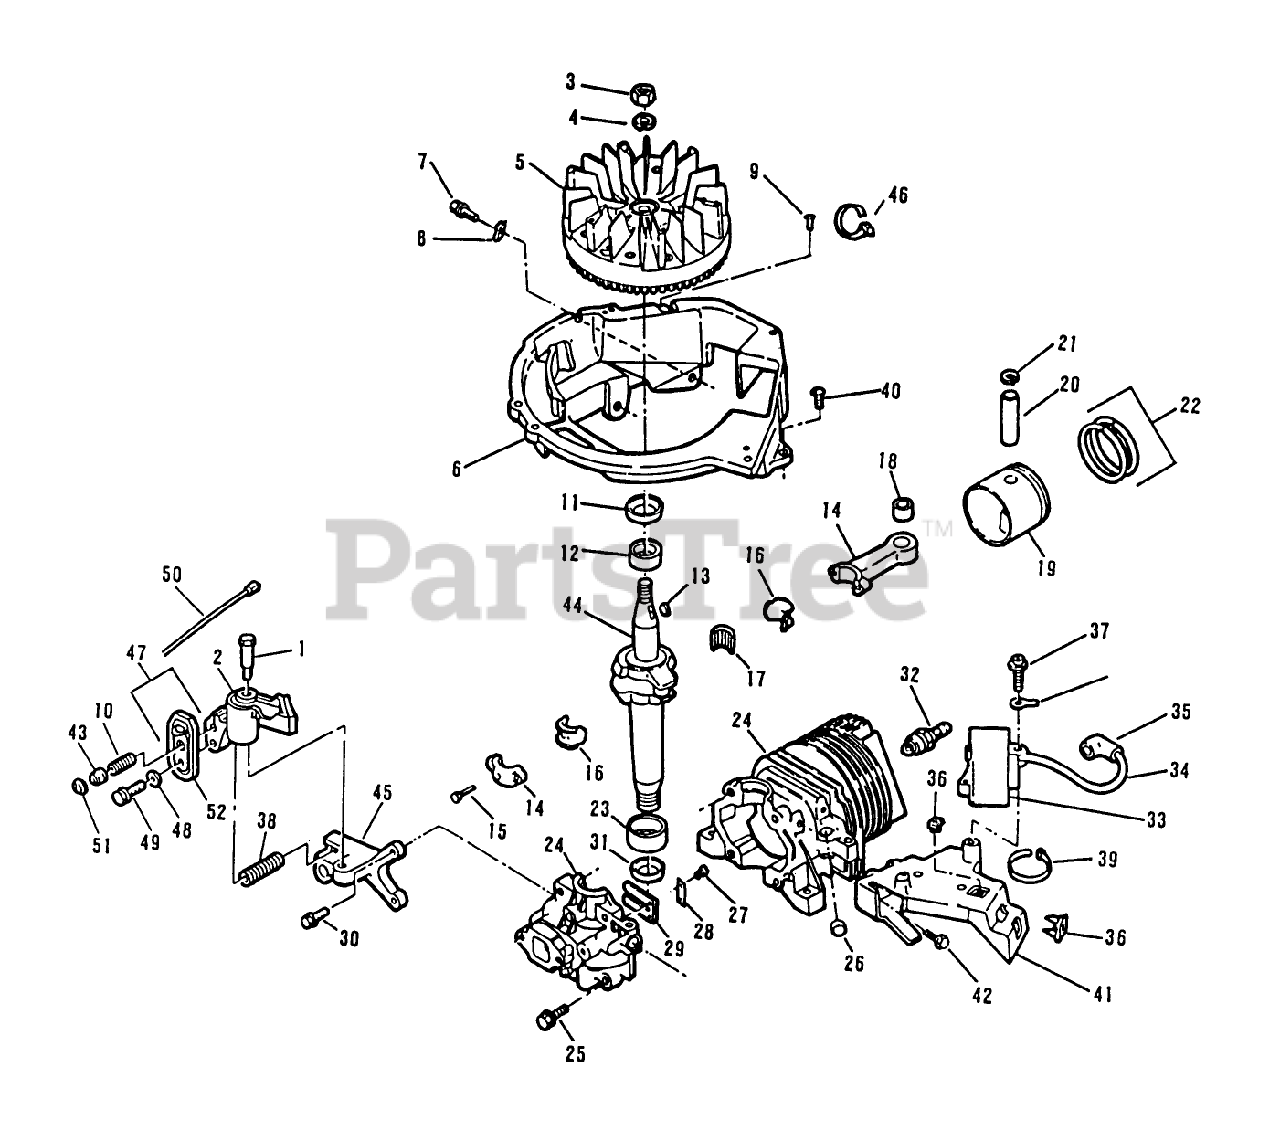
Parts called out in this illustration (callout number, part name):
3	NUT
5	FLYWHEEL ASSY F
6	BASE SHROUD F
7	SCREW-SEMS
9	SCREW F
10	SPRING
11	SEAL-OIL
12	BEARING V
13	KEY
15	SCREW-HSH
16	LINER ASM
17	BEARING-NEEDLE
18	BEARING AY F
21	RING-RETAINING
23	BEARING V
25	SCREW-H.W.HD. F
26	PLUG-CORE VF
27	SCREW-HH
28	PLATE-BACKUP, REED
30	SCREW
31	SEAL-OIL
34	HT LEAD&COVER XEV
36	NUT-CLIP
38	SPRING-BRAKE
40	SCREW F
41	C.D. BRKT F
43	ACTUATOR-LEVER, BRAKE
45	BRACKET-BRAKE F
48	WASHER
50	WIRE LEAD AY F
51	RETAINER S
